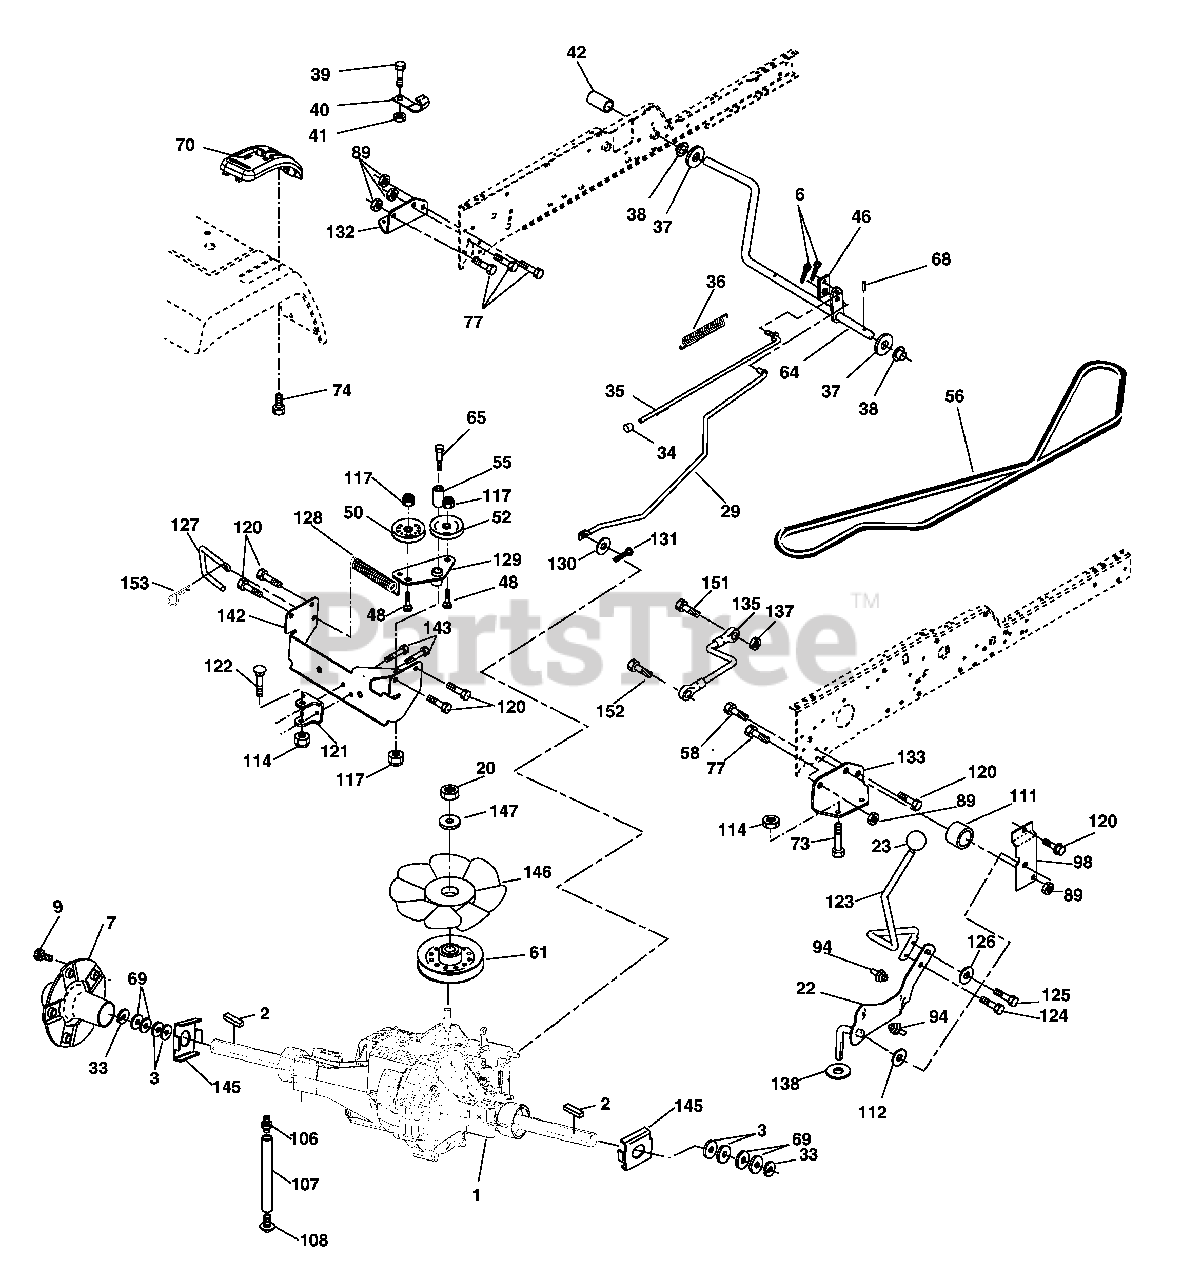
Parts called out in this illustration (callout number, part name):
1	Transaxle Hydro Gear
2	Key Sq. 1/4 x 2.5
6	Pin, Cotter
7	Wheel, Hub Assembly
22	Lever Asm Shift
29	Brake, Rod
34	Cap, Parking Brake
35	Rod, Parking Brake
36	Spring, Drive Ground
37	Washer 25/32 x 1-1/4 x 16 Ga.
39	Screw, Fin. #10-24 x 1
40	Actuator, Interlock VGT
41	Nut Centerlock 10-24 Unc
42	Cover, Pedal
46	Retainer, Spring
48	Bolt Rdhd 3/8-16 x 1-3/4 Gr. 5
50	Pulley, Idler, Flat
52	Pulley, Idler, Grooved
55	Bearing, Idler
58	Bolt Fin Hex 7/16-14 x 1-1/2
61	Pulley, Transaxle
64	Shaft, Brake Pedal
65	Bolt, Shoulder
70	Console Automatic YT/GT
73	Bolt Hex Flghd 5/16-18 x 3 Gr. 5
74	Screw Hex Wsh. Hi-Lo 1/4-1/2
77	Bolt Fin Hex 7/16-14 x 1
89	Nut Crownlock 7/16-14 Unc
94	Fastener Christmas Tree
98	Bracket Shift
106	O-Ring Asm Hydro Gear
107	Line Fuel Hydro 15" VGT
108	Cap Asm Vent Hydro Gear
111	Spacer Shift Lever VGTH
112	Washer Nylon High Temp
114	Nut Lock Hex W/Ins 5/16-18 Unc
117	Nut, Lock Flg. 3/8-16
120	Screw 3/8-16 x .75
121	Bracket Strap Torque
122	Bolt RDHDSQ 5/16-18 unc x 2-1/2
124	Bolt Shoulder 5/16-18 x .561
125	Screw 5/16-18 x 5/8
126	Washer SRRTD 5/16 ID x 1 x .125
127	Link Control Clutch
128	Spring Drive GRND
129	Bracket Asm Idler Tensioning
130	Washer 13/32 x 5/8 x 16 Ga.
131	Pin Cotter 3/32 x 3/4
132	Bracket Mtg Hydro 3500 LH VGT
133	Bracket Mtg Hydro 3500 RH VGT
135	Link Asm Control Hydro 3500
137	Nut Lock 5/16-18 NC Thd.
138	Washer Thrust 5/8 x 1.10 x 1/32
142	Strap Torque HG-3500
143	Screw Thdrol 5/16-18 x 3/4
145	Washer Axle Flange HG-3000
146	Fan 7" Hydro
148	Screw 3/8-16 x 1.0-1/4
151	Bolt Hex 5/16-18 x 7/8
152	Bolt Hex 5/16 x 1 W/Patch
153	Spring, Retainer
